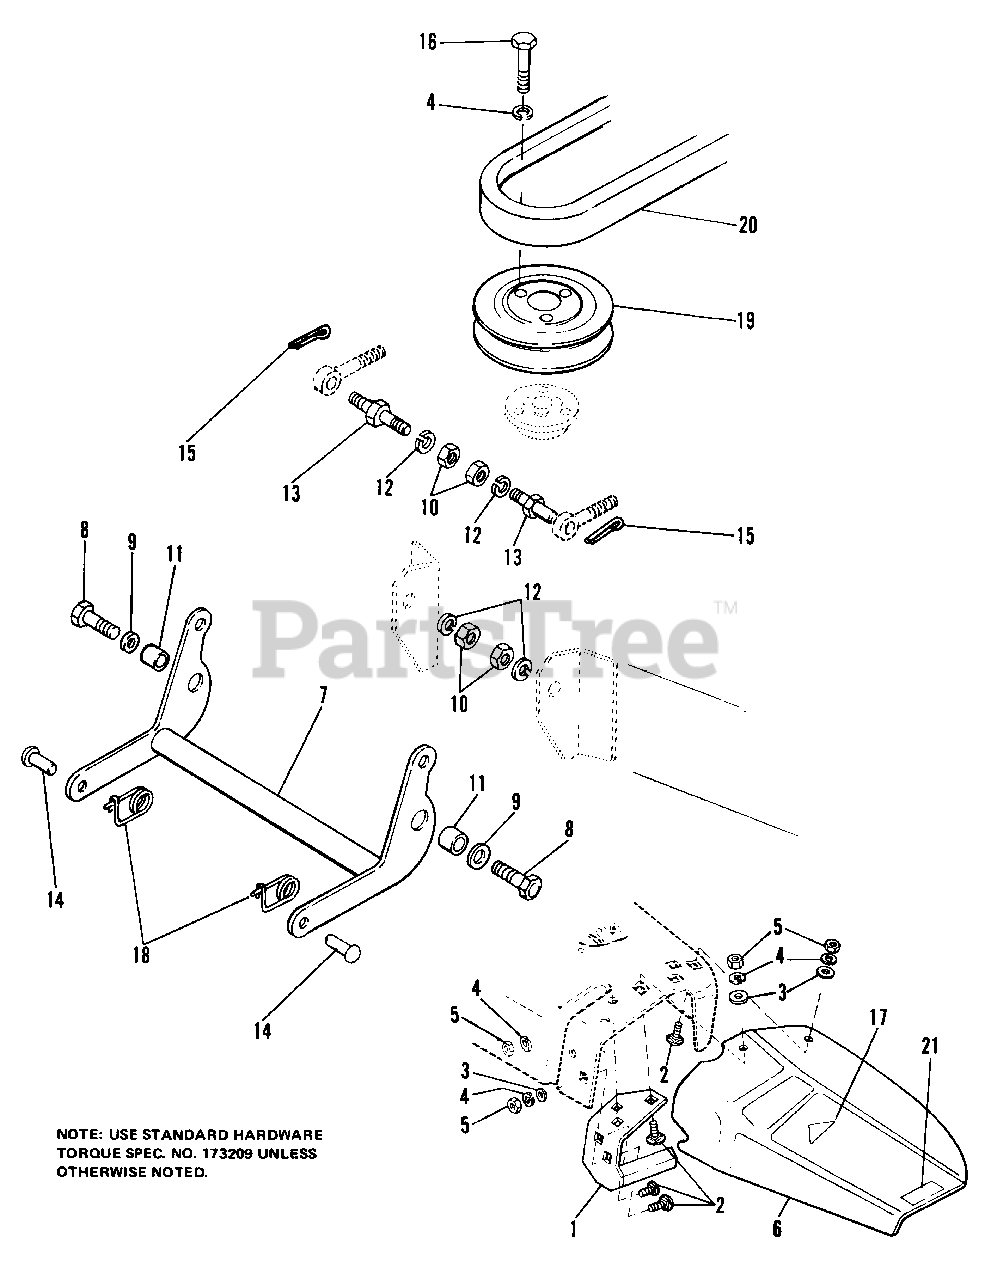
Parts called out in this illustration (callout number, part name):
1	GUARD ASSY, Stone
2	CARRIAGE Bolt 3/8-16 x 1-1/4
3	WASHER, Special
4	LOCKWASHER. 3/8
5	NUT, Hex Full, 3/8-16
6	DEFLECTOR
7	ROCKER ARM ASSY
8	CAPSCREW, Hex Hd., 1/2-13 x 1-1/4
9	WASHER, Plain, 7/16
10	NUT, Hex Full, 1/2-13
12	LOCKWASHER. 1/2
14	PlN
15	PIN, Cotter, 1/8 x 1
16	CAPSCREW, Hex Hd., 3/8-16 x 1-3/4
17	DECAL, OPEI
18	CLIP, Safety Pin
20	"V" BELT, PTO
21	DECAL, Danger
